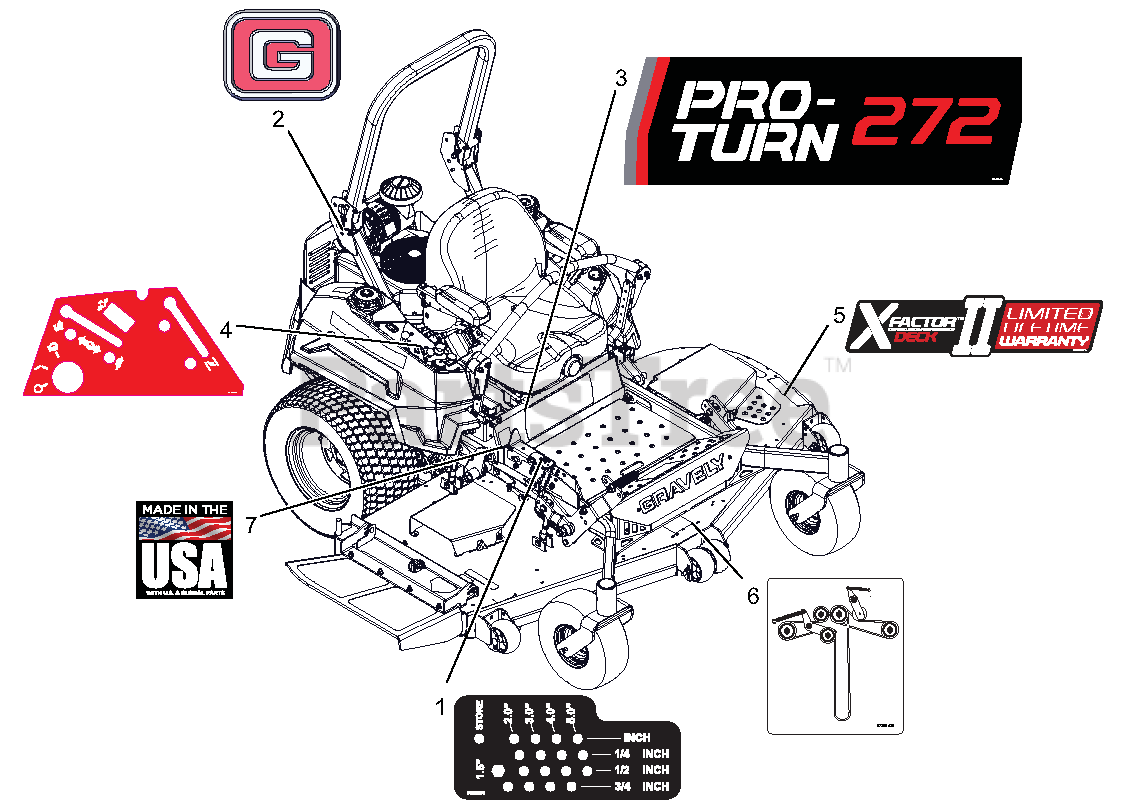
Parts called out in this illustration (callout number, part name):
1	DECAL, HEIGHT OF CUT
2	DECAL, GRAVELY BRAND
3	DECAL, PRO-TURN 272
4	DECAL, NON-EFI CONTROL PANEL
5	DECAL, X-FACTOR DECK
6	DCL,BELT ROUTE-RH BK-SIDE IDLR
7	DECAL, MADE IN USA
